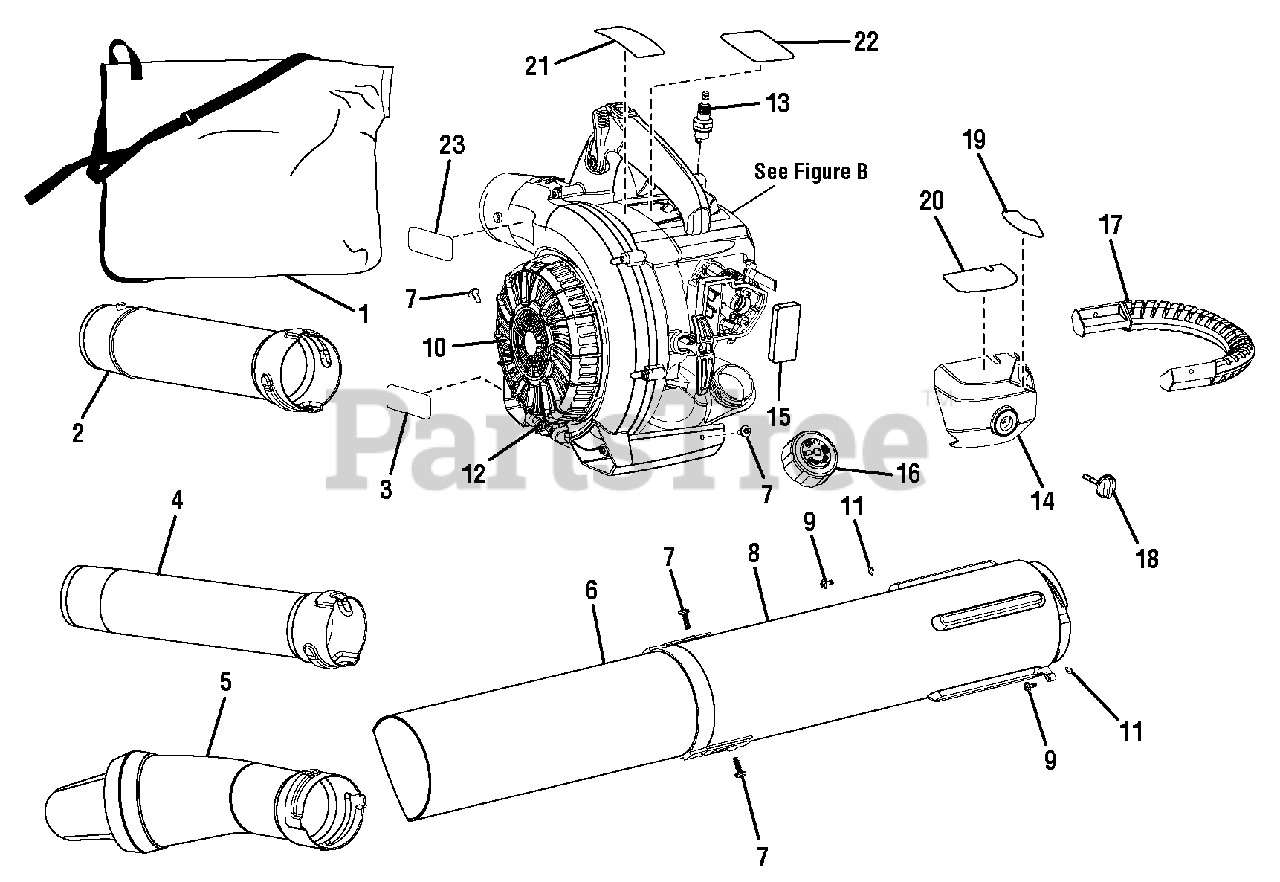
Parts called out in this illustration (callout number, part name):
1	Vacuum Bag w/Shoulder Strap
2	Upper Blower Tube
3	Combustion Label
4	Sweeper Nozzle
5	Vacuum Bag Adaptor
6	Lower Vacuum Tube
7	Vacuum Tube Screw (10-14 x 1/2 in., T25 Torx Truss Hd. T.F.)
8	Upper Vacuum Tube
9	Screw (1/4-20 x 3/4 in., Soc. Hd.)
10	Vacuum Door
12	Vacuum Door Spring
13	Spark Plug (RCJ6Y)
14	Air Filter Cover
16	Fuel Cap Assembly
17	Vacuum Handle
18	Knob
19	Choke Label
20	Starting Label
21	Warning Label
22	Logo Label (Small)
23	Logo Label (Large)
